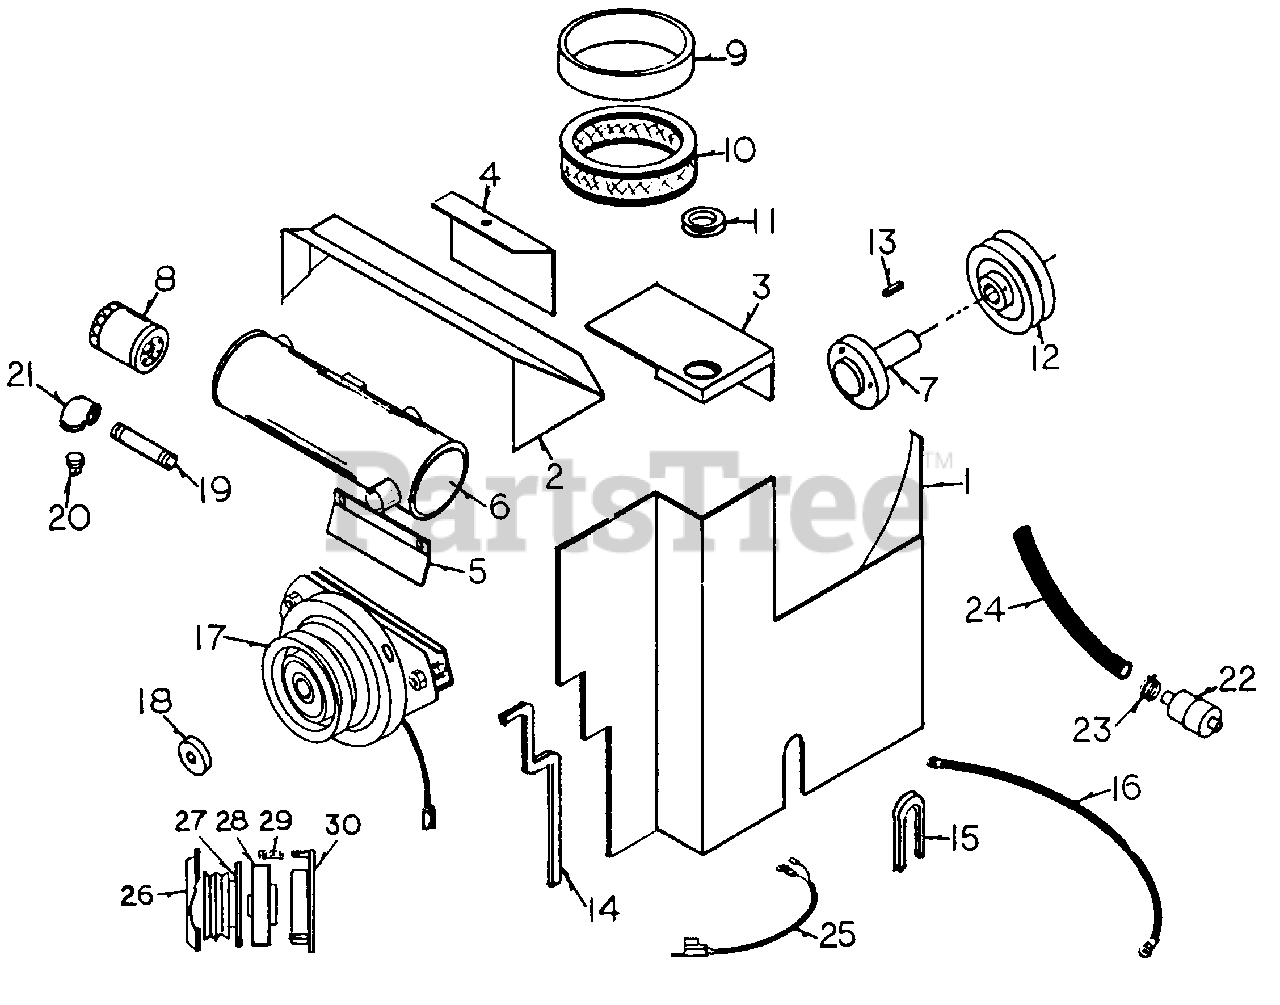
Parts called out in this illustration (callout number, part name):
1	Heat Shield, Part A
2	Heat Shleld, Part B
3	Heat Shleld, Part C
4	Heat Shield, Part D
7	Onan Engine Shaft
8	Onan Oil Filter
9	Onan Filter Element
10	Onan Filter Cartridge
13	Key Stock, 1/4" x 1"
17	Electric Clutch
18	Clutch Retainer Washer
19	Pipe Nipple, 3/8"
20	Pipe Plug, 3/8"
21	Pipe Elbow, 3/8"
22	Fuel Fllter
23	Fuel Line Clamp
24	Fuel Line, 38"
25	Starter Harness
27	Clutch Amature
29	Clutch Brake Spring
